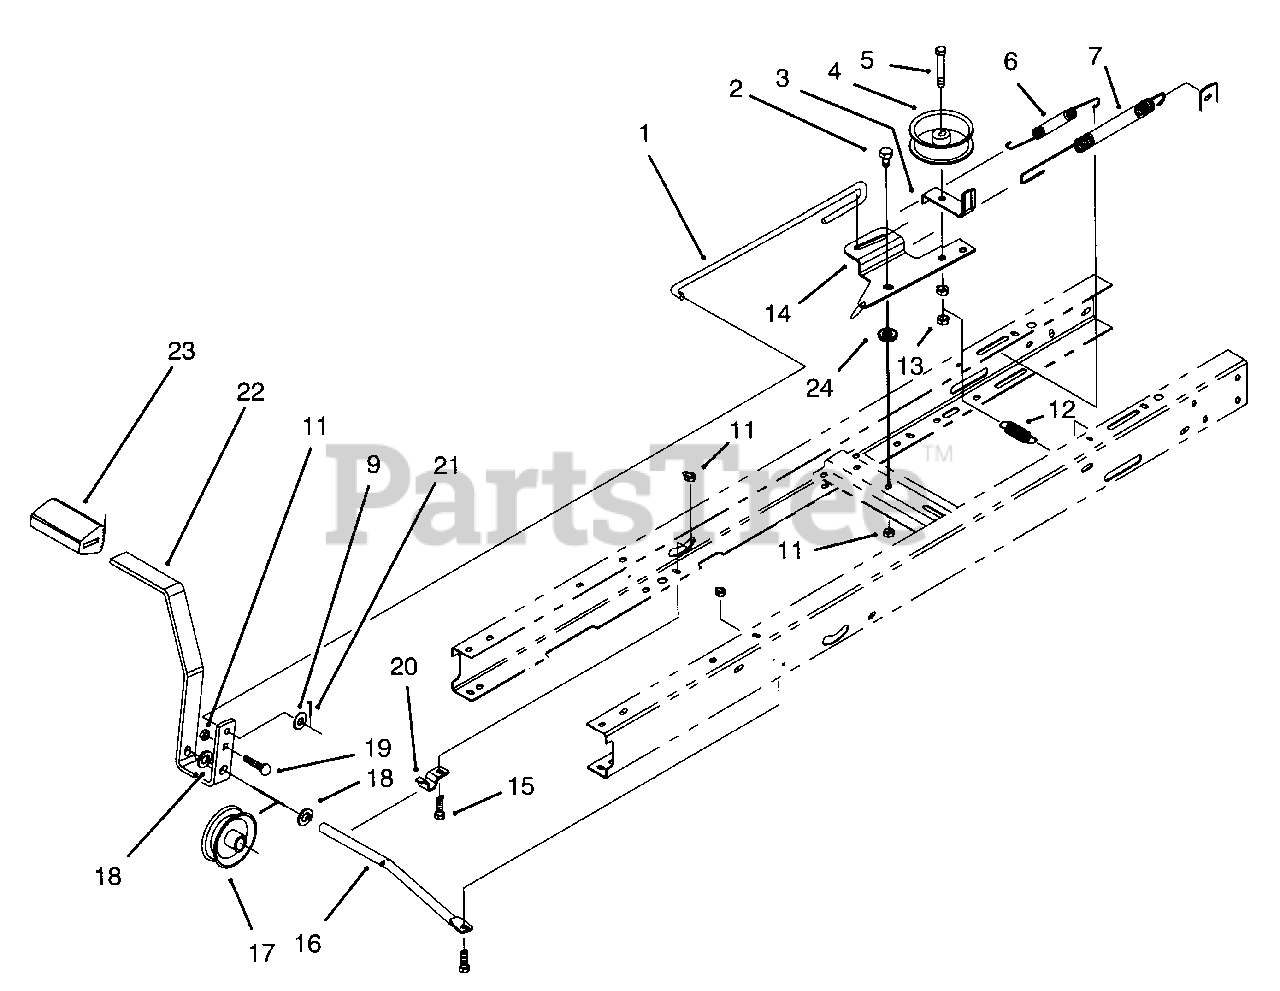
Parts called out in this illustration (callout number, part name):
1	Rod-Clutch/Brake
2	Bolt-Shoulder
3	Guide-Idler Belt
4	Pulley-Flat Idler
5	Screw-Hex Hd. Cap
6	Spring-Pedal Return
7	Spring-Brake
9	Washer-Flat
11	Nut-Lock
12	Spring-Extension
13	Nut-Lock
14	Arm-Idler
15	Screw-Hex Hd. Cap
16	Rod-Pedal Pivot
17	Pulley-Cable
18	Washer-Flat
19	Bolt-Carriage
20	Clamp-Shift Pivot
21	Pin-Cotter
22	Pedal-Clutch/Brake
23	Pad-Pedal
24	Washer-Fender
